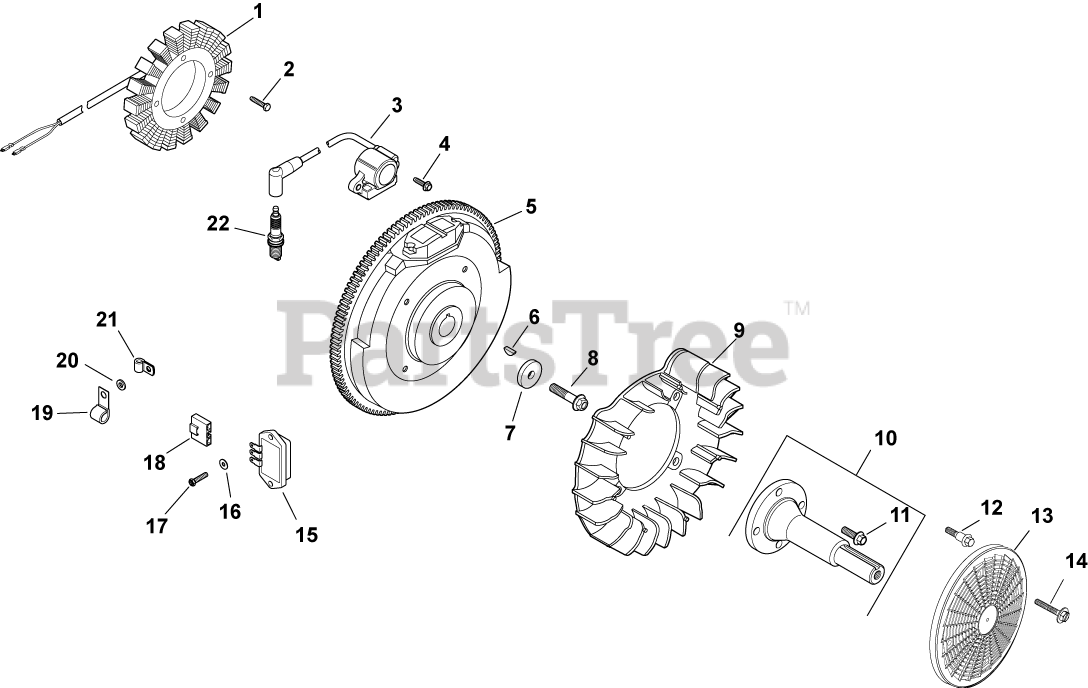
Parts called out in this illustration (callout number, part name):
1	KIT, 15 / 20 AMP STATOR
2	SCREW, M5X0.8X25 - (#25086402S)
3	KIT, MODULE IGNTN (CDI FIXED)
4	SCREW, FLG THD FRM M5X.8X20-(#25086399S)
5	FLYWHEEL, PAINTED-USE 24 025 55-S
6	KEY, 3/16" X 5/8"
7	WASHER, FLAT 13/32"
8	SCREW, FLG M10X1.5X45 - (#25086361S)
9	FAN USE 24 755 253-S
10	SHAFT, FRONT DRIVE
11	SCREW, FLG M8X1.25X25
12	BOLT, SHOULDER
13	SCREEN, GRASS-USE 24 162 45-S
14	SCREW, FLG SEMS M4X.7X25
15	REG/RECT-15 AMP (KM)-USE 41 403 10-S
16	WASHER, FLAT 7/32"
17	SCREW, PHL HD #11-16X7/8"
18	CONNECTOR, BODY (KM)-USE 25 155 41-S
19	CLIP, CABLE
20	WASHER, FLAT 1/4" (O.D. 1/2")
21	CLIP, TUBE & WIRING (KM)
22	PLUG, SPARK (STD)
